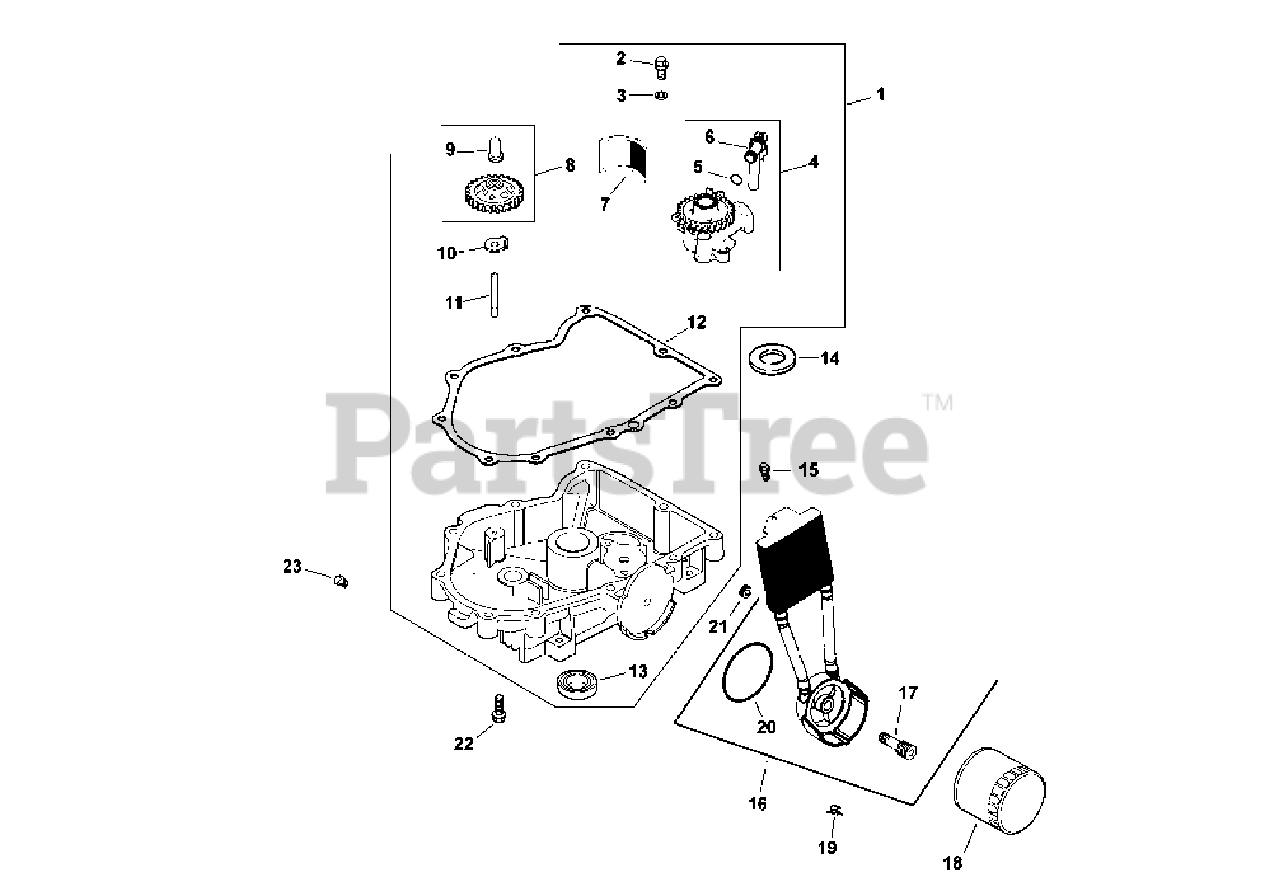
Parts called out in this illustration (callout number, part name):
1	Kit Oil Pan Assembly (Inc. 2-13)
2	Flange Screw, M6 x 1.0 x 25
3	Flat Washer, 6 mm
4	Oil Pump Assembly Kit (Inc. 5 & 6)
5	Oil Pick-Up O-Ring
6	Oil Pick-Up Tube Kit
8	Governor Gear Kit w/Pin (Inc. 9)
9	Governor Regulating Pin
11	Governor Gear Shaft
12	Oil Pan Gasket Kit (Select-A-Seal)
14	Thrust Shim (Black .686 mm)
15	Tap Screw, M6 x 1.7 x 18
16	Oil Cooler Kit (Inc. 17 & 20)
17	Oil Filter Nipple
19	Plastic Nut (Black)
20	Oil Cooler O-Ring
21	Countersink Pipe Plug, 3/8
22	Flange Screw, M8 x 1.25 x 45
23	Pipe Plug, 3/8
